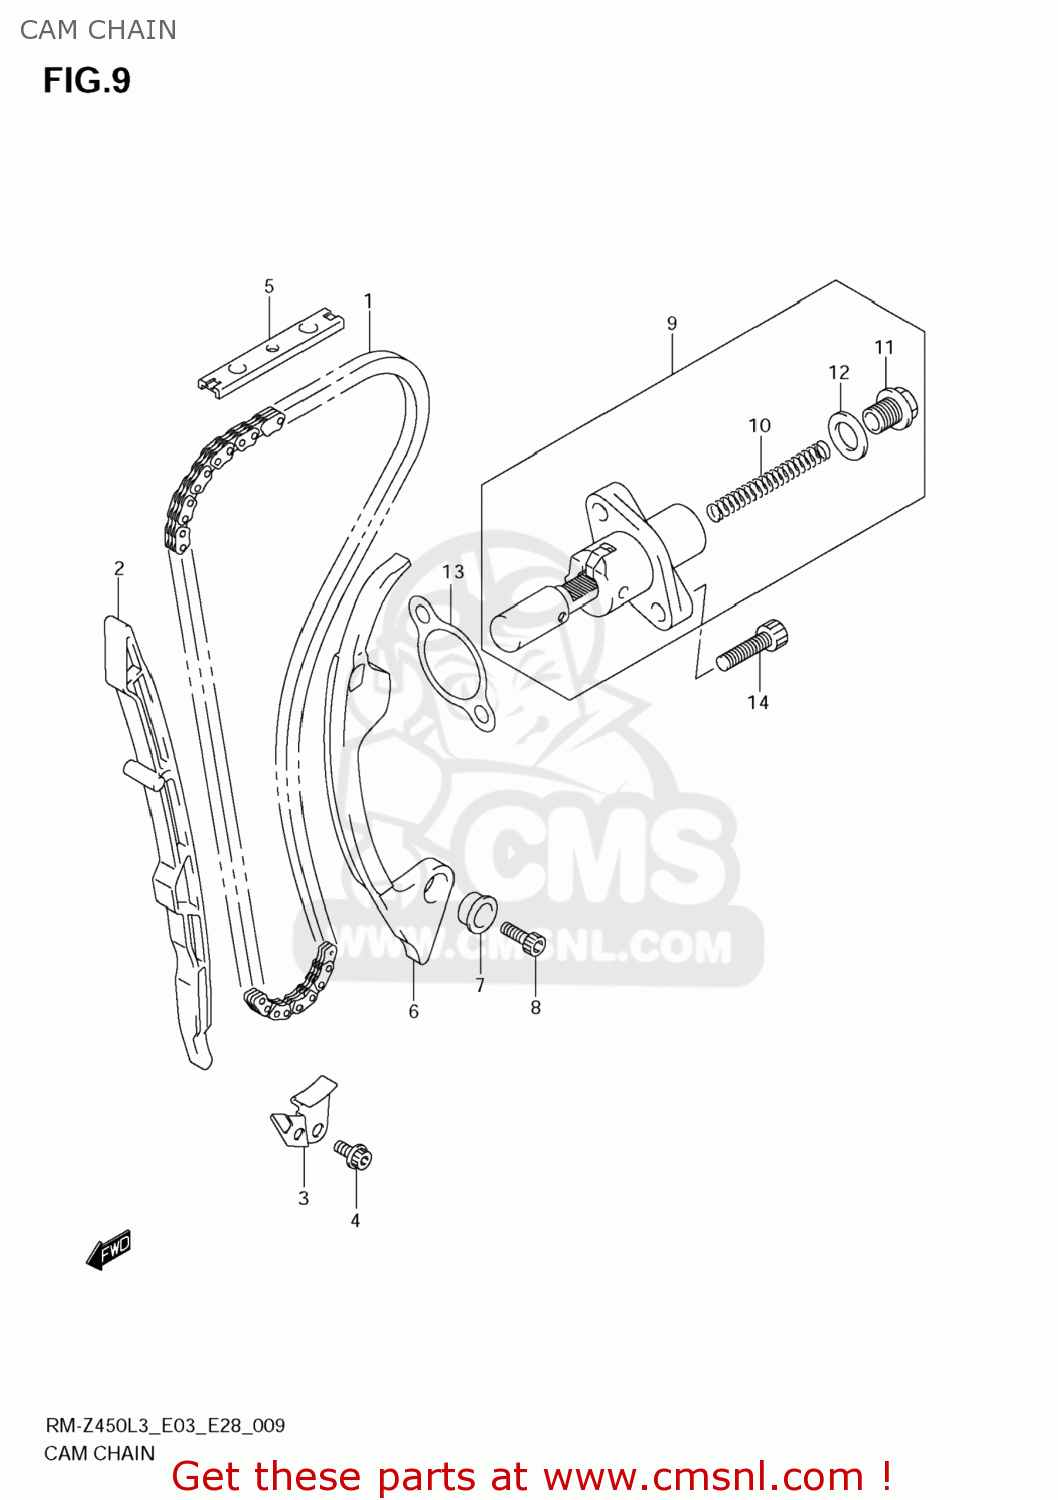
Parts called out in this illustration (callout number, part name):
1	CHAIN,CAMSHAFT DRIVE
2	GUIDE,CAM CHAIN NO.1
3	RETAINER,CAM CHAIN GUIDE NO.1
4	BOLT
5	GUIDE,CAM CHAIN NO.2
6	TENSIONER,CAM CHAIN
7	SPACER,CAM CHAIN TENSIONER
8	BOLT
9	ADJUSTER ASSY,TENSIONER
10	SPRING
11	PLUG,FR TENSIONER ADJ
12	GASKET,TENSIONER ADJUSTER (NAS)
13	GASKET,TENSIONER ADJUSTER (NAS)
14	BOLT
